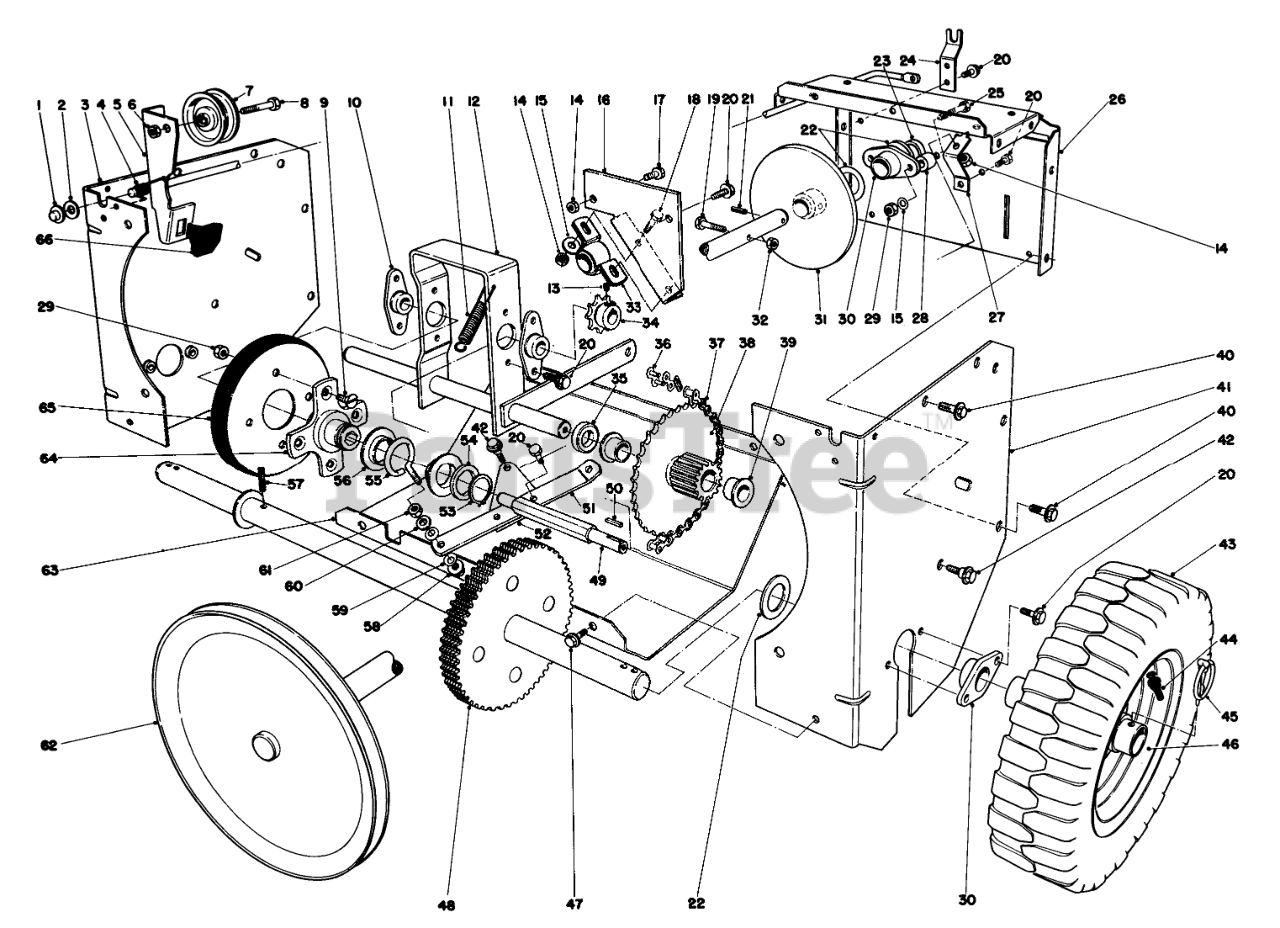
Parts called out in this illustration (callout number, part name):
1	PUSH NUT
2	WASHER-FLAT
3	RH TRACT SIDE PLT R
4	TORSION CLUTCH SPRING
5	clutch Rod (Incl. Ref. #66)
6	NUT-HEX
7	PULLEY-IDLER
8	SCREW-HH
9	5/16-18X5/8 FLT HD MS
10	BEARING-WHEEL, FRICTION
11	TENSION SPRING
12	PIVOT SHAFT WA B
13	SCREW-HSH
14	NUT-LOCK, NI
15	WASHER-PLAIN
16	SHAFT SUPT BRKT B
17	SCREW-HH
18	SCREW-HH
19	SCREW-HH
20	SCREW-HWHTF
21	PIN-ROLL, SLOTTED
22	WASHER
23	DRIVE SHAFT SPACER
24	CLUTCH ROD SUPPORT
25	SCREW-HH
26	CENTER FRAME R
27	PIVOT BRACKET
28	BRG STANDOFF
29	Nut
30	AXLE BEARING
31	FRICTION PLT WA
32	NUT-LOCK, CONE
33	PILLOW BLOCK BRG
34	SPROCKET
35	COSHAFT SPACER
36	LINK-CONNECTING
37	ROLLER-CHAIN
38	Gear & Bushing (Incl. Ref. #39)
39	BUSHING
40	SCREW-HHFTF
41	LH TRACT SIDE PLT R
42	SHOULDER SCREW
43	Tire
44	STEM-VALVE
45	PIN-LYNCH
46	Wheel
47	SCREW-HWH
48	AXLE & GEAR WA
49	FRICTION WHL SHAFT
51	SHIFT LINKAGE
52	PIVOT PLATE
53	RING-RETAINING
54	WASHER-THRUST
55	SLIDER RING COLLAR
56	SLIDER RING
57	PIN-ROLL, SLOTTED
58	NUT-LOCK, FLANGE
59	WASHER-SPRING
60	WASHER-FLAT
61	Nut
62	PULLEY/SHFT WA
63	LOWER SHIELD R
64	TRACTION DISC HUB
65	FRICTION WHEEL
66	Brake Pad
